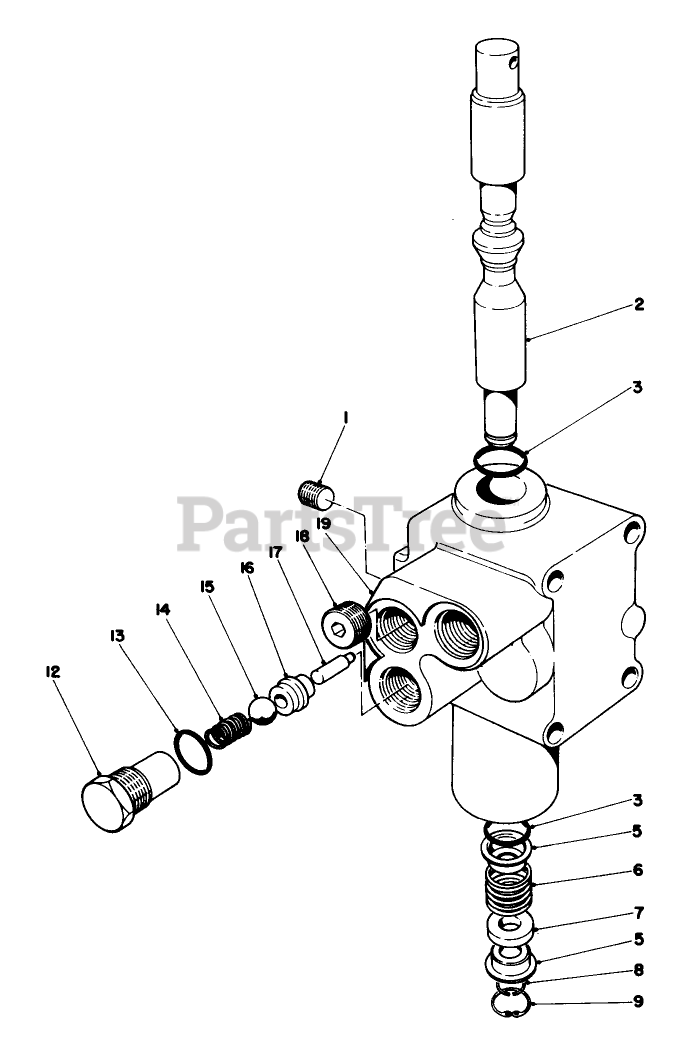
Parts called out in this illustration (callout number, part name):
2	SPOOL
3	O-RING
5	RETAINER
6	SPRING
7	FLOAT SPACER
8	RING-SNAP
9	RING-SNAP
13	O-RING
14	SPRING
16	SEAT-VALVE
19	Bode
